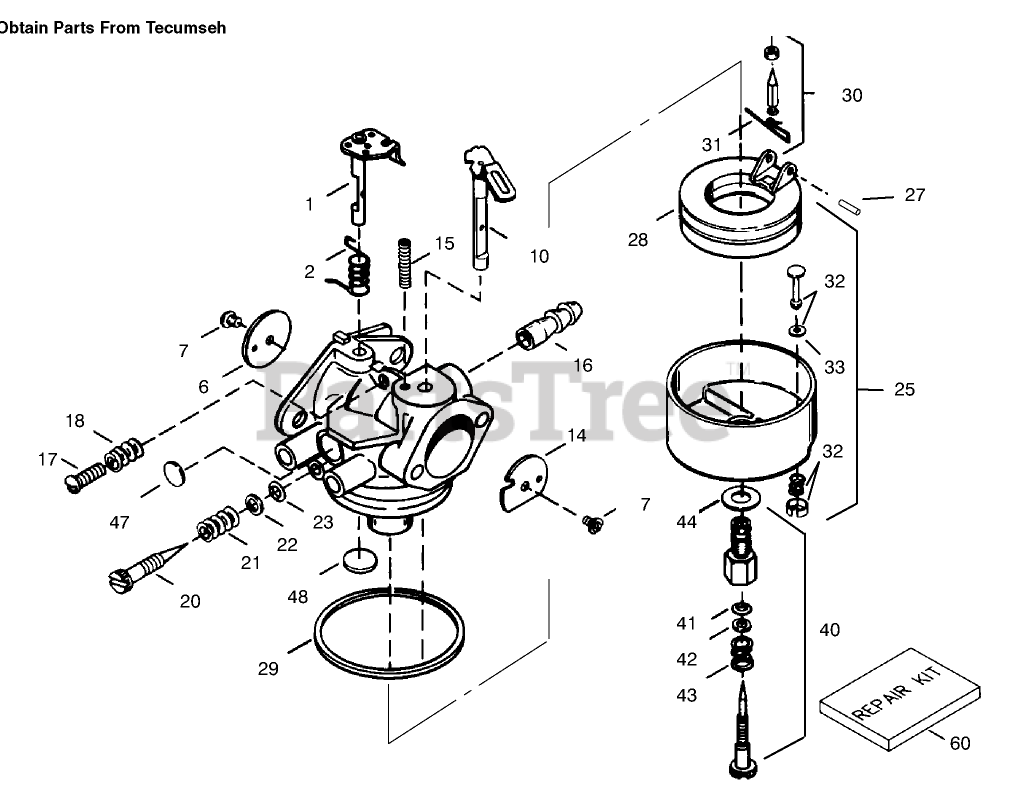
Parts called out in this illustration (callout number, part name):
1	Throttle Shaft and Lever ASM
2	Spring-Return, Throttle
6	Shutter-Throttle
7	Screw-Shutter
10	Choke Shaft and Lever ASM
14	Shutter-Choke
15	Spring-Positioning, Choke
16	Fitting-Fuel
17	Screw-Throttle Crack Screw / Idle Speed
18	Spring-Tension
20	Screw-Idle Mix
21	Spring-Tension
22	Washer
23	ORing
25	Float Bowl Asm. (Incl. Ref. # 32, 33)
27	Shaft-Float
28	Float
29	O Ring-Bowl, Float
30	Inlet Needle, Seat Clip Assy. (Incl. No. 13)
31	Clip-Spring
32	Bowl Drain ASM
33	Gasket-Plunger, Drain
40	Adjustment Screw Assy.,Main (Incl. Ref. #5A,21,23 30)
41	ORing
42	Washer
43	Spring
44	Washer-Bowl Nut
47	Plug-Welch, Idle Mixture Well
48	Plug-Welch, Atmospheric Vent
60	Kit-Repair
